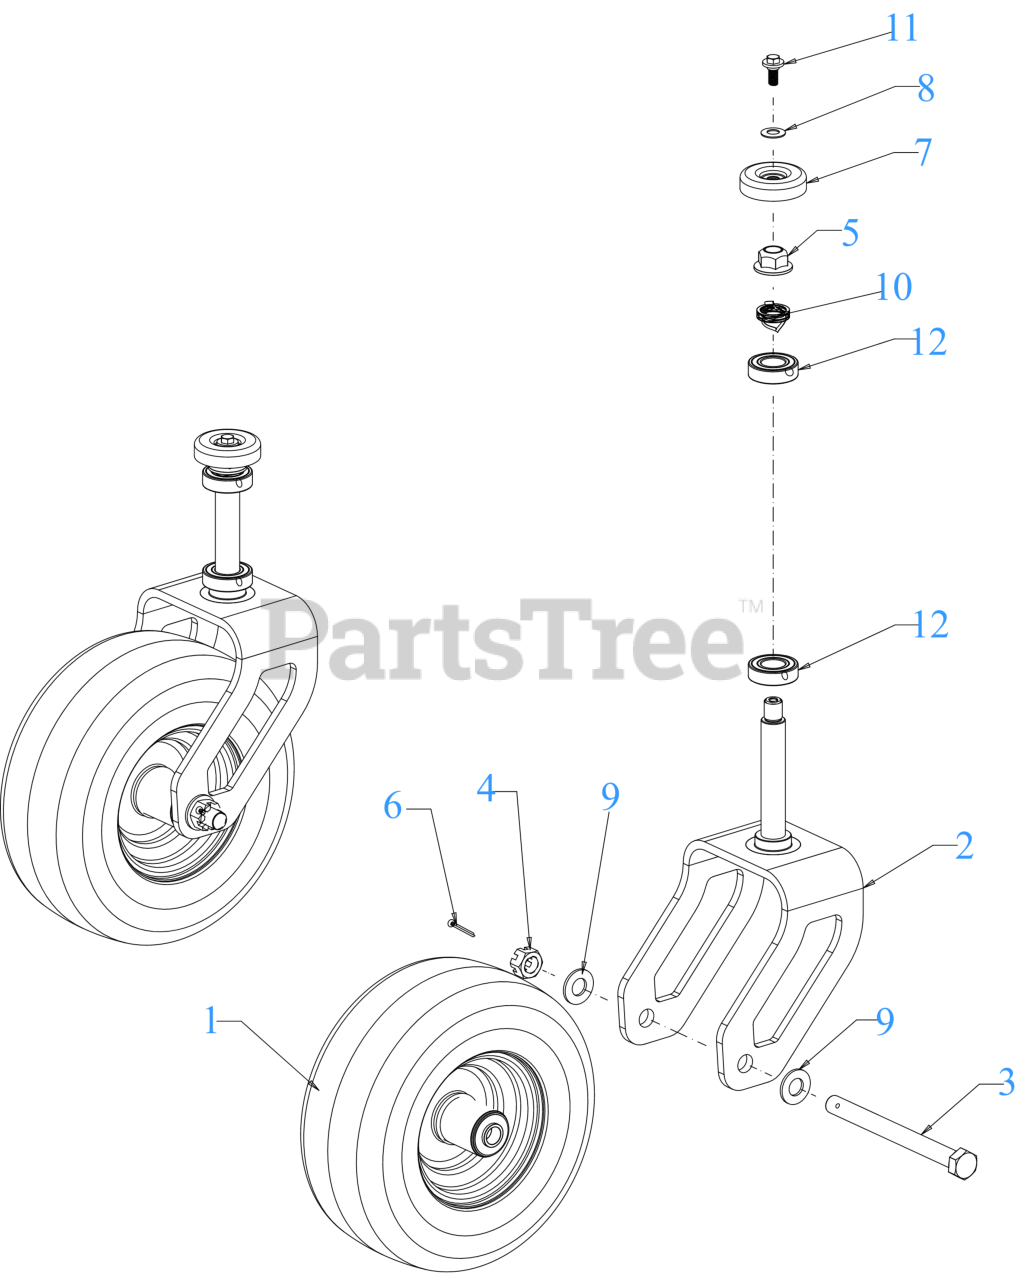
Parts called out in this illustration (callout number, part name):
1	WHEEL 13x5-6 (SEMI PNEU)
2	YOKE
3	HEX HEAD CAP SCREW 3/4-16x8.25
4	HEX NUT CASTLE 3/4-16
5	FLANGE LOCK NUT 3/4-16 TOP LOCK
6	COTTER PIN-5/32 DIA
7	AXLE CAP 2.5"
8	BELL WASHER
9	FLAT WASHER
10	WAVE WASHER
12	BALL BEARING (1.0 x 52 x 15)
